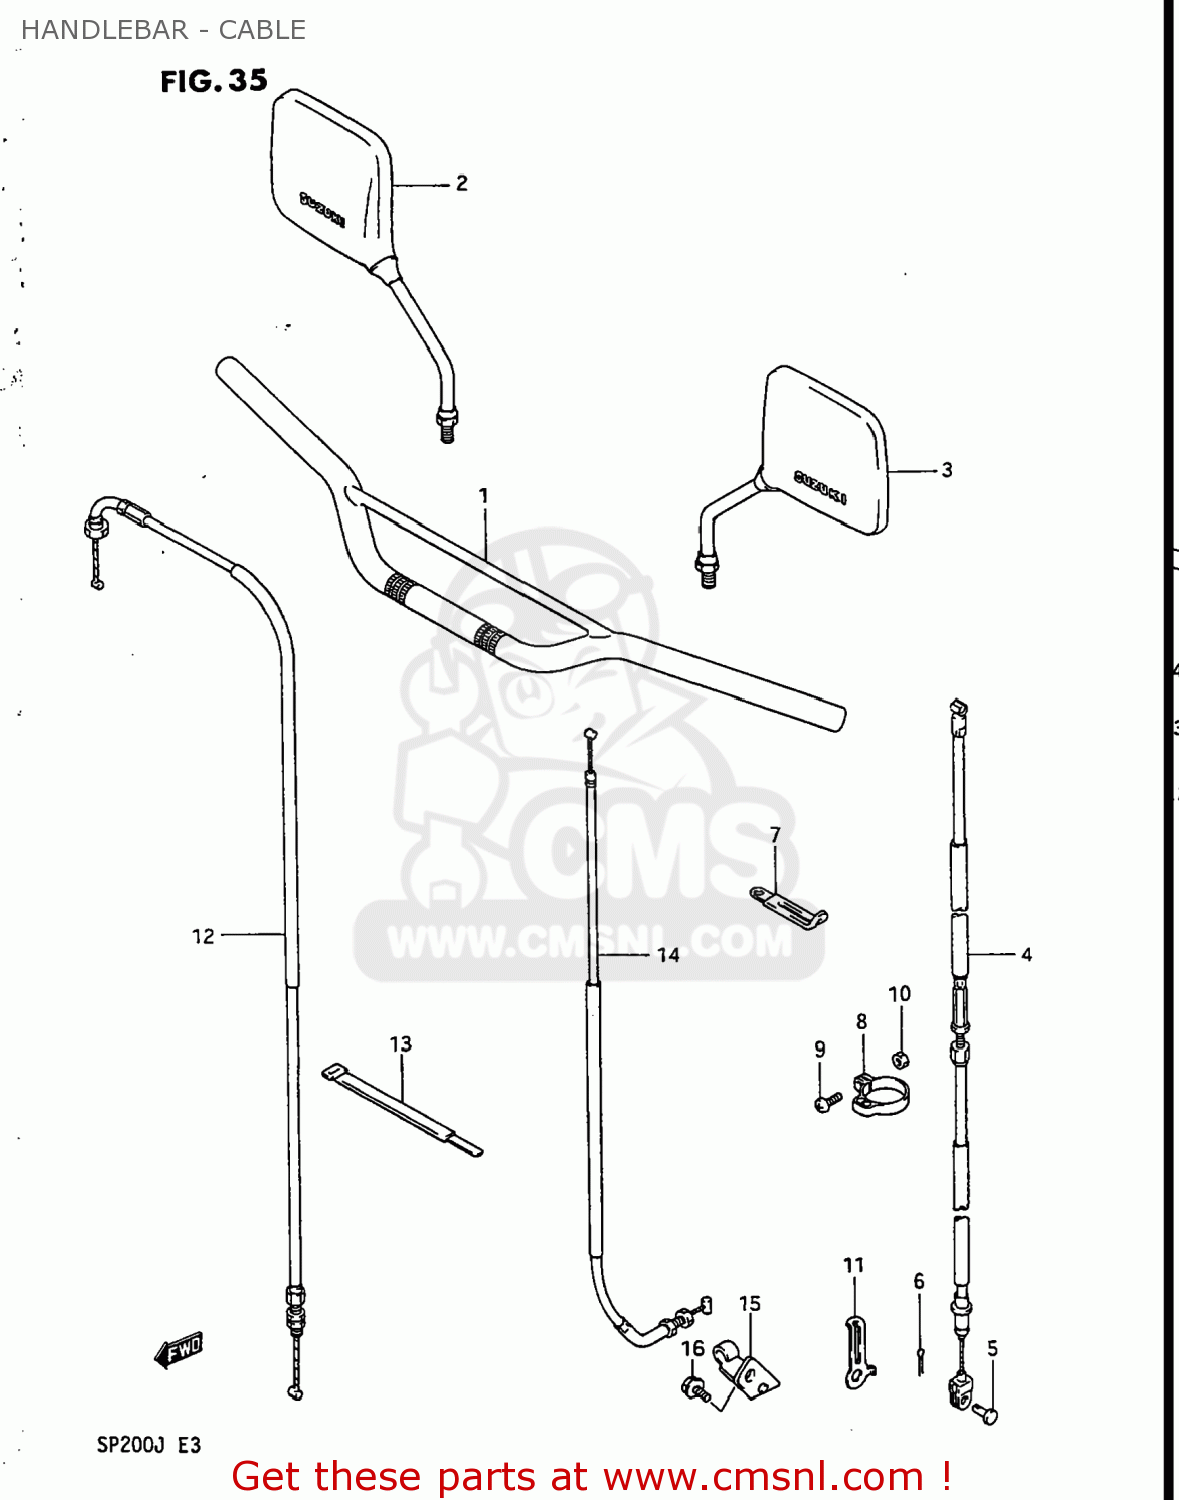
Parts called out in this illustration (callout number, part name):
1	HANDLEBAR
2	MIRROR ASSEMBLY,REAR VIEW
3	MIRROR ASSEMBLY,LEFT
4	CABLE ASSY,CLUTCH
5	PIN(L:15)
6	PIN
7	CLAMP
8	CLAMP,CABLE
9	SCREW
10	NUT 5MM
11	CLAMP,CABLE
12	CABLE ASSY,THROTTLE
13	CLAMP
14	CABLE ASSY,DECOMP
15	BRACKET,DECOMP CABLE
16	BOLT 6X12
